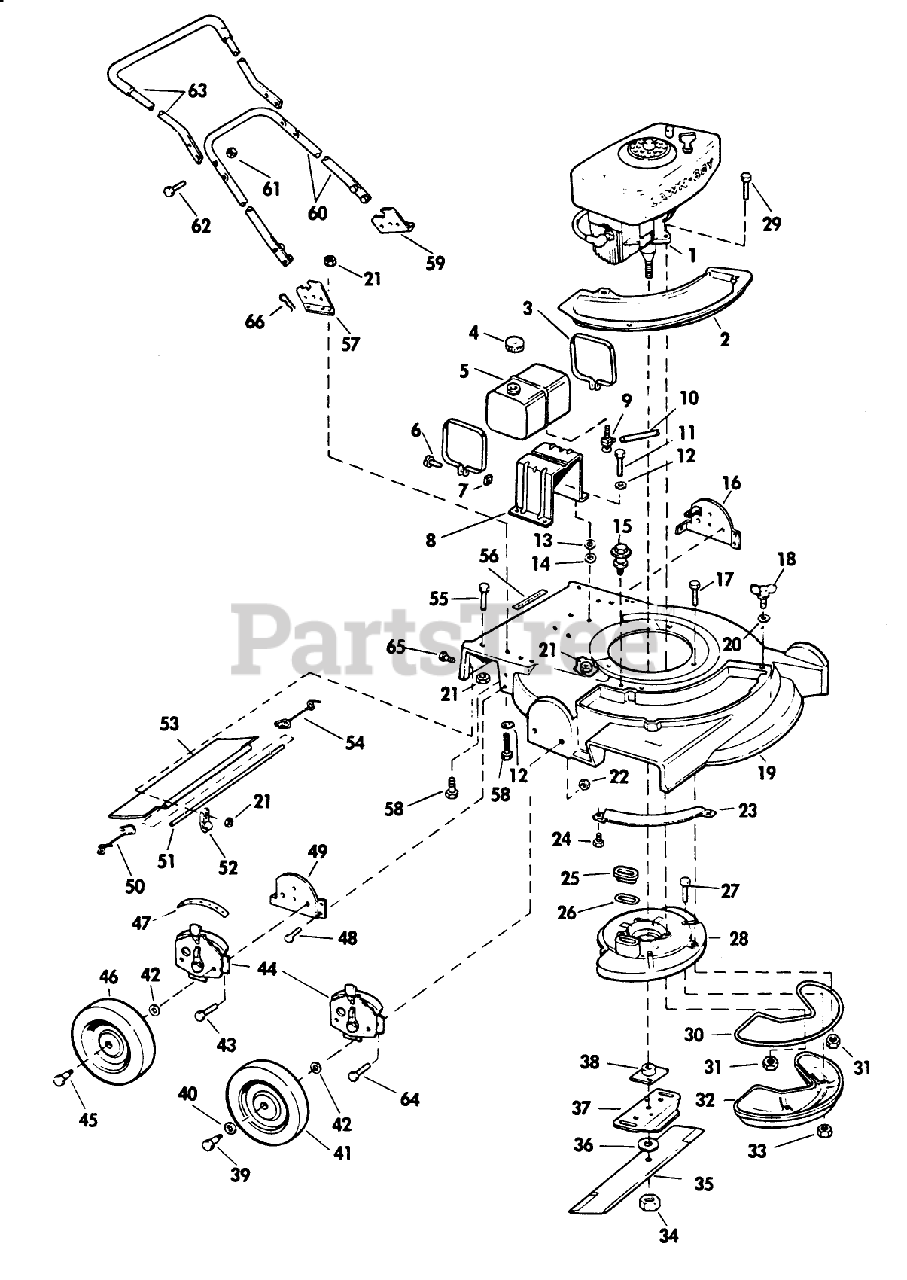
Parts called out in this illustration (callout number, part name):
1	See Note #1 at bottom of this page.
7	Nut
9	VALVE&SCREEN SM
11	BOLT PIONEER
14	WASHER
17	SCREW
18	WING SCREW LAWRE
21	LOCKNUT E
22	NUT-LOCK F
23	BAR-TOE
25	SLEEVE
26	GASKET S
27	SCREW
31	NUT-LOCK F
34	NUT-BLADE
36	WASHER
38	PLATE AND COLLAR ASM
39	BOLT WHEEL
40	Washer
42	WASHER WROUGHT
45	BOLT-SHOULDER
50	SPRING;TRAILING SHIELD RH
51	ROD 21" ADVANCE
52	CLAMP ROD KMC
54	SPRIG T/SHLD ASOC
55	SCREW
58	BOLT RB&W
61	LOCKNUT E
62	SCREW
65	Screw
